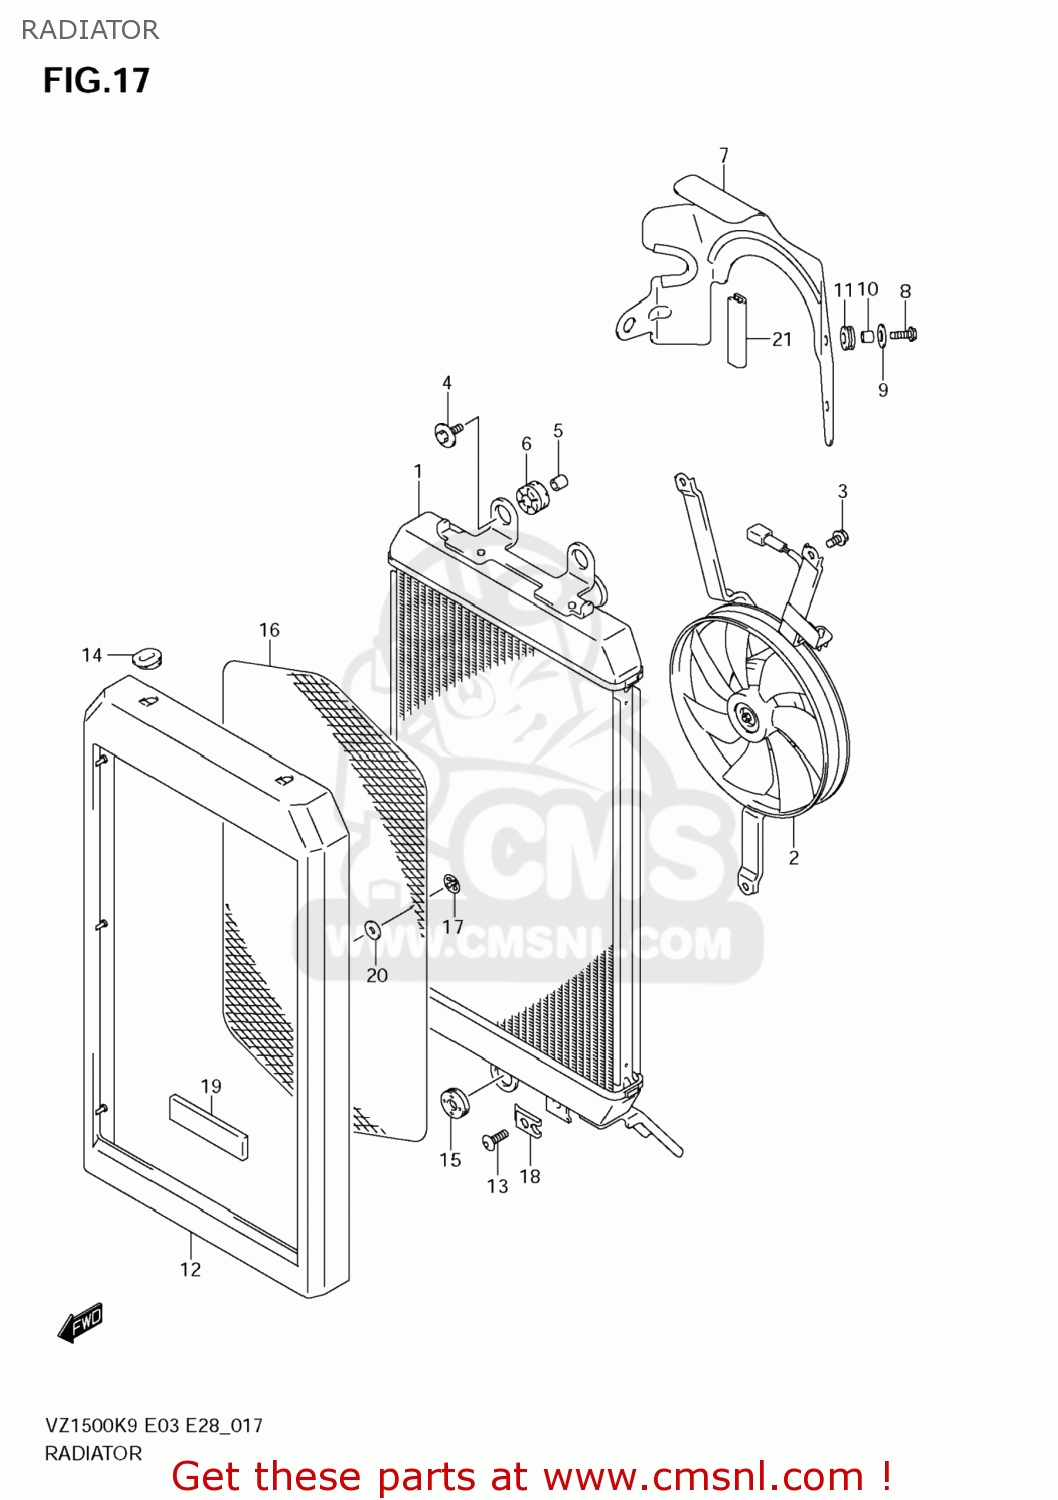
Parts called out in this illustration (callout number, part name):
1	RADIATOR ASSY,
2	FAN ASSY,RADIATOR
3	BOLT
4	BOLT(6X25)
5	SPACER(6.5X10X12)
6	CUSHION
7	SHIELD,RADIATO
8	BOLT
9	WASHER(6.5X20X1.2)
10	SPACER(6.2X8.3X5.7)
11	CUSHION
12	COVER,RADIATOR
13	SCREW(6X16)
14	CUSHION
15	CUSHION
16	NET,RADIATOR COVER
17	NUT
18	NUT
19	CUSHION,LEG SHIELD COVER
20	CUSHION
21	MOLDING,RADIATOR COVER
